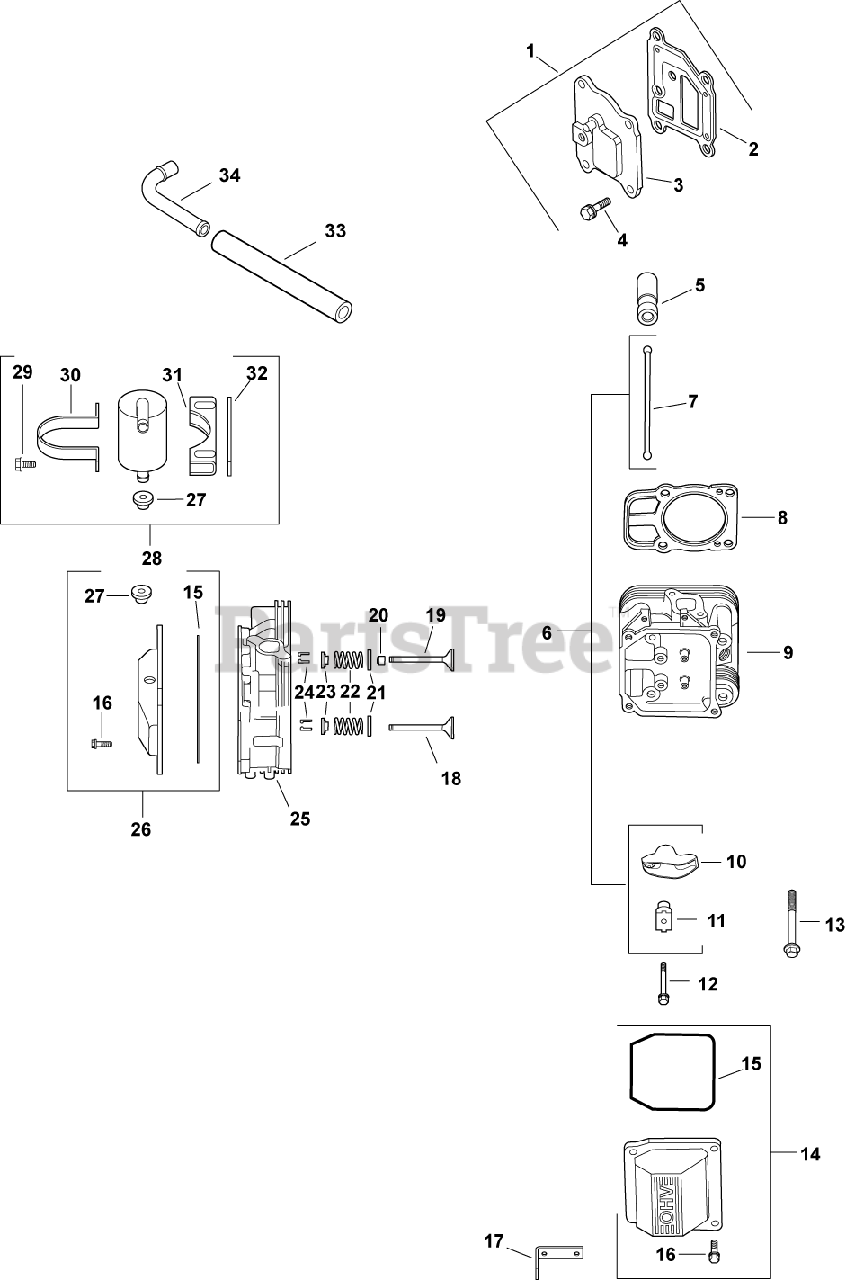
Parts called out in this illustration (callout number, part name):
1	KIT, BREATHER COVER W/GASKET
2	GASKET, BREATHER-USE 24 041 67-S
3	COVER, BREATHER -USE 24 096 125-S
4	SCREW,FLG THD FRM M6X1.0X20-(#25086396S)
5	LIFTER, HYDRAULIC VALVE-USE 25 351 10-S
6	KIT, VALVE TRAIN
7	ROD, PUSH
8	KIT, GSKT CYL HD (C22-23 674CC)
9	HEAD, ASSEM CYLINDER #2 -USE 24 318 113-
10	ARM, ROCKER
11	PIVOT, ROCKER ARM
12	SCREW, FLG M6X1.0X34
13	SCREW - USE 62 086 08-S
14	KIT, VALVE COVER-PLAIN
15	O-RING (YELLOW), VALVE COVER
16	SCREW, FLG M6X1.0X30
17	STRAP, LIFTING-USE 25 445 03-S
18	VALVE, EXHAUST (STD) - USE 32 016 01-S
19	VALVE, INTAKE (STD)
20	SEAL, VALVE STEM - (#2503214S)
21	RETAINER, SPRING
22	SPRING, VALVE
23	RETAINER, VALVE SPRING - USE 25 173 28-S
24	KIT, RETAINER
25	HEAD, ASSEM CYLINDER #1 -USE 24 318 105-
26	KIT, VALVE COVER
27	GROMMET, RUBBER
28	KIT, BREATHR SEPARATR-(#24755241S)
29	SCREW,FLG THD FRM M5X0.8X16-(#25086398S)
30	STRAP, BREATHER - USE 24 755 241-S
31	BRACKET, BREATHER SEPARATOR
32	SPACER
33	HOSE, BREATHER (WAWB)-USE 24 326 63-S
2401602-S	VALVE, EXHAUST (.25)
2401702-S	VALVE, INTAKE (.25)
